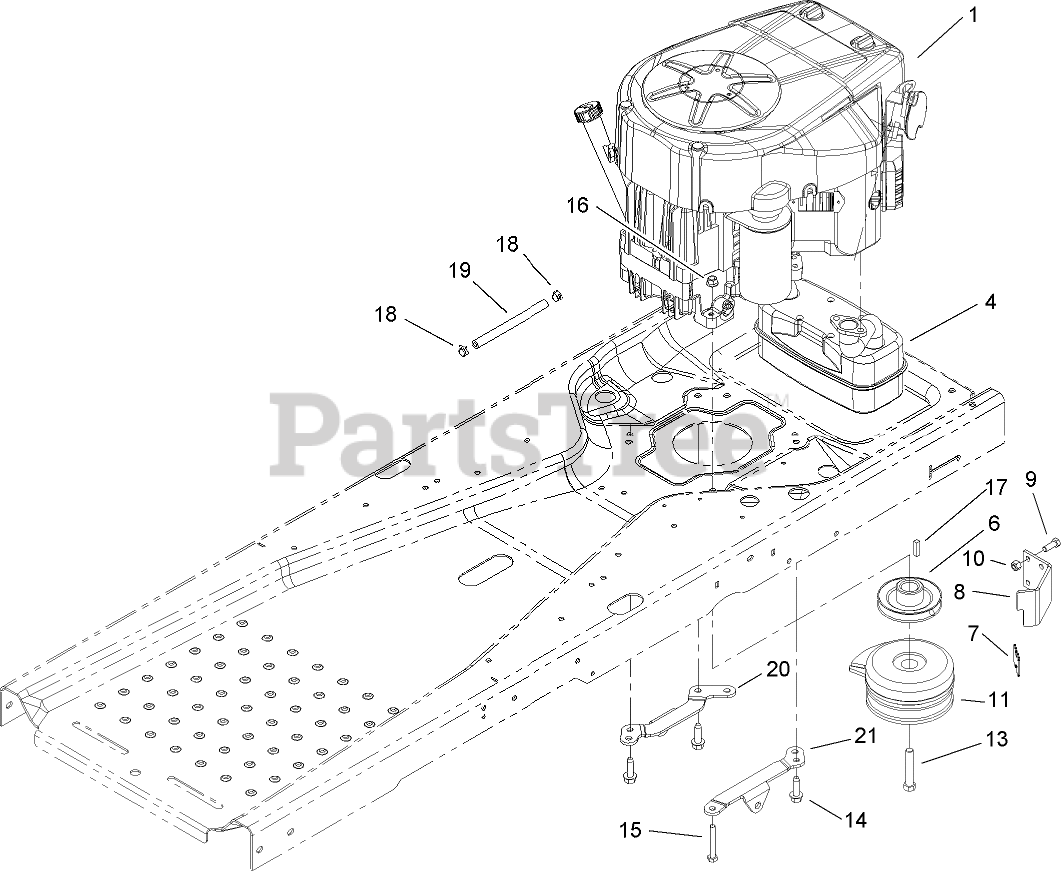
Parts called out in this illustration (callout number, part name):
4	MUFFLER-KAWASAKI TWIN
6	PULLEY-ENGINE
7	BUMPER
8	STOP-CLUTCH
9	SCREW-HH
10	NUT-LOCK, NI
11	CLUTCH-ELECTRIC, PTO
13	SCREW-HH
14	SCREW-TAPTITE
15	SCREW-HH
16	NUT-LOCK, NI
18	CLAMP-HOSE
19	HOSE-FUEL
20	SUPPORT-HYDRO, RH
21	SUPPORT-HYDRO, LH
